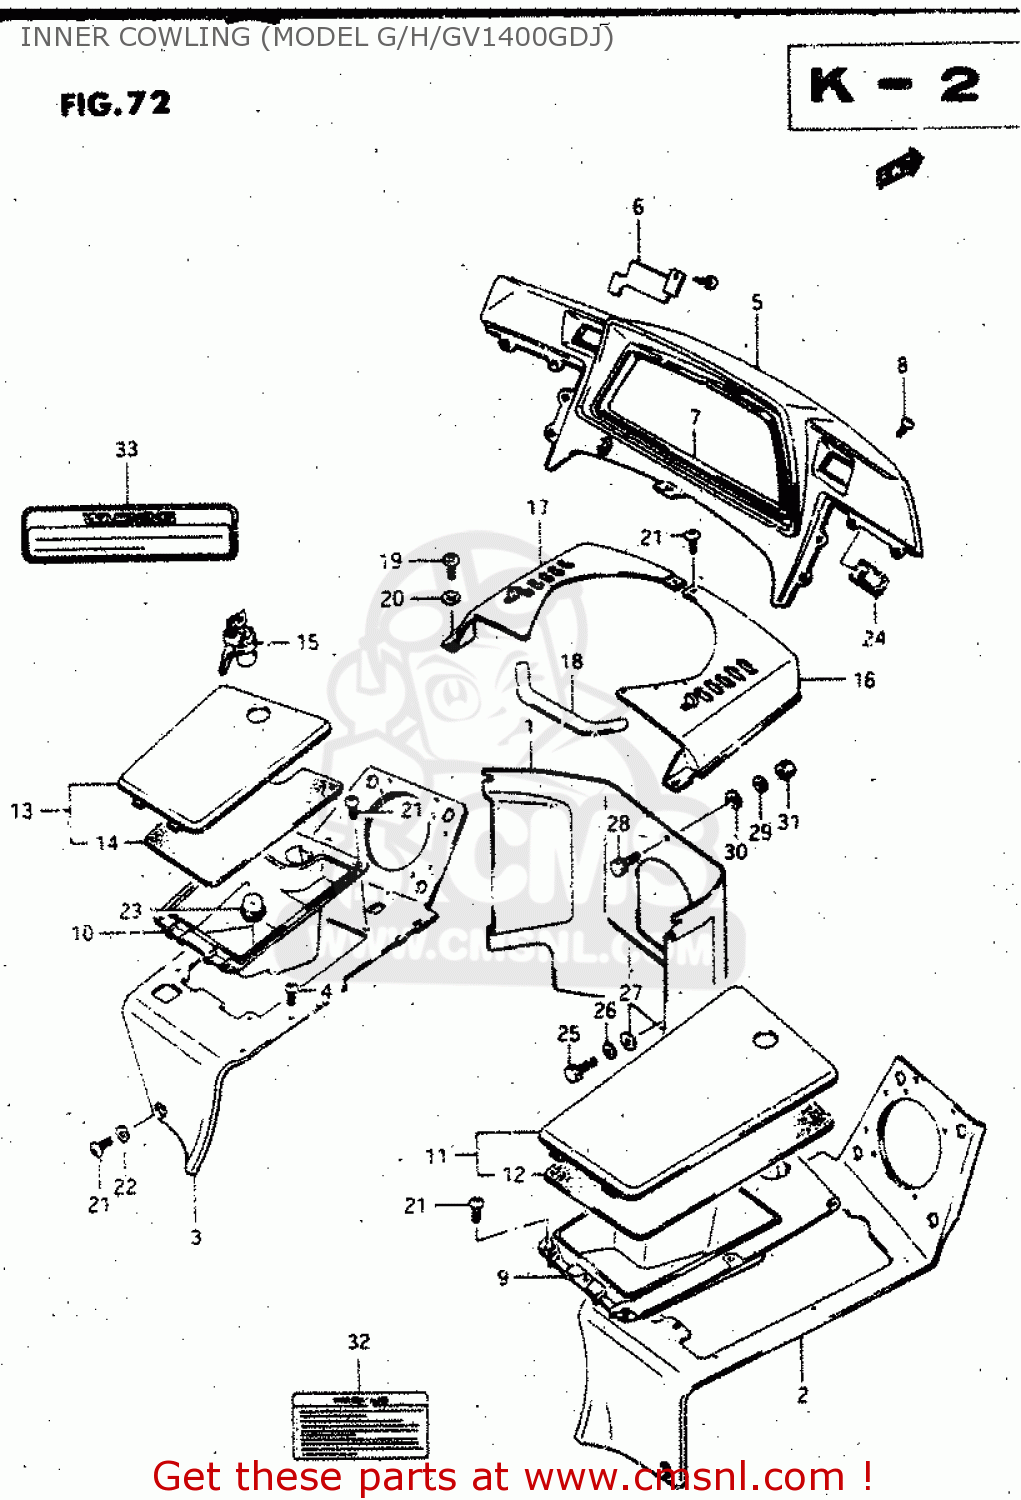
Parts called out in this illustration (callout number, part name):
1	COVER,COWLING,INNER
2	PANEL,COWLING,R
3	PANEL,COWLING,L
4	SCREW
5	COVER ASSY,METER
6	COVER,METER COVER HOLE
7	MOLDING,METER COVER
8	SCREW
9	BOX, COWL PANEL RH
10	BOX,COWLING PANEL,LEFT
11	LID,COWLING BOX RH
12	SEAL,LID,RIGHT
13	LID,COWLING BOX LH
14	SEAL,LID,LEFT
15	LOCK SET,TOOL HOLDER
16	COVER ASSY,FRAME HEAD,R(BLACK)
17	COVER ASSY,FRAME HEAD,L(BLACK)
18	SEAL,FRAME HEAD
19	SCREW
20	WASHER,5.5X12X
21	SCREW
22	WASHER (4.3X13X0.80)
23	CAP,COWLING PANEL BOX
24	CAP,RADIO IND
25	BOLT
26	LOCK WASHER
27	WASHER,5.5X12X
28	BOLT
29	LOCK WASHER
30	WASHER,5.5X12X
31	NUT
32	LABEL (WARNING)
33	LABEL (WARNING COVER CO
